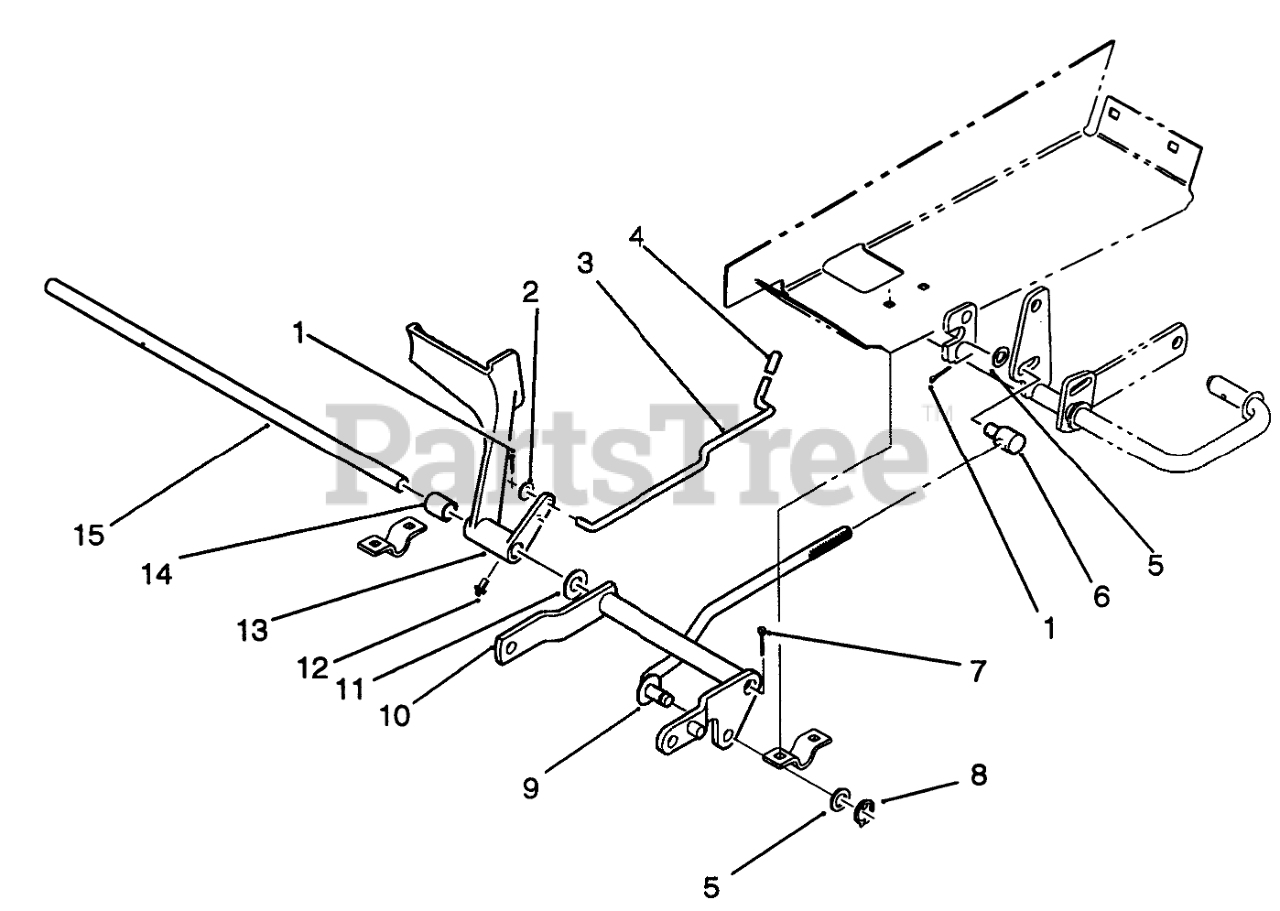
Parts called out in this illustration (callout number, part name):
1	PIN-COTTER
2	NUT-LOCK, NI
3	ROD-BRAKE LOCK
5	WASHER-FLAT
6	ROD-TRUNNION LIFT
7	PIN-COTTER
8	RING-RETAINING, EXTERNAL
10	Arm
11	Washer
12	FITTING-GREASE
13	Pedal-Brake
14	SPACER
15	SHAFT
